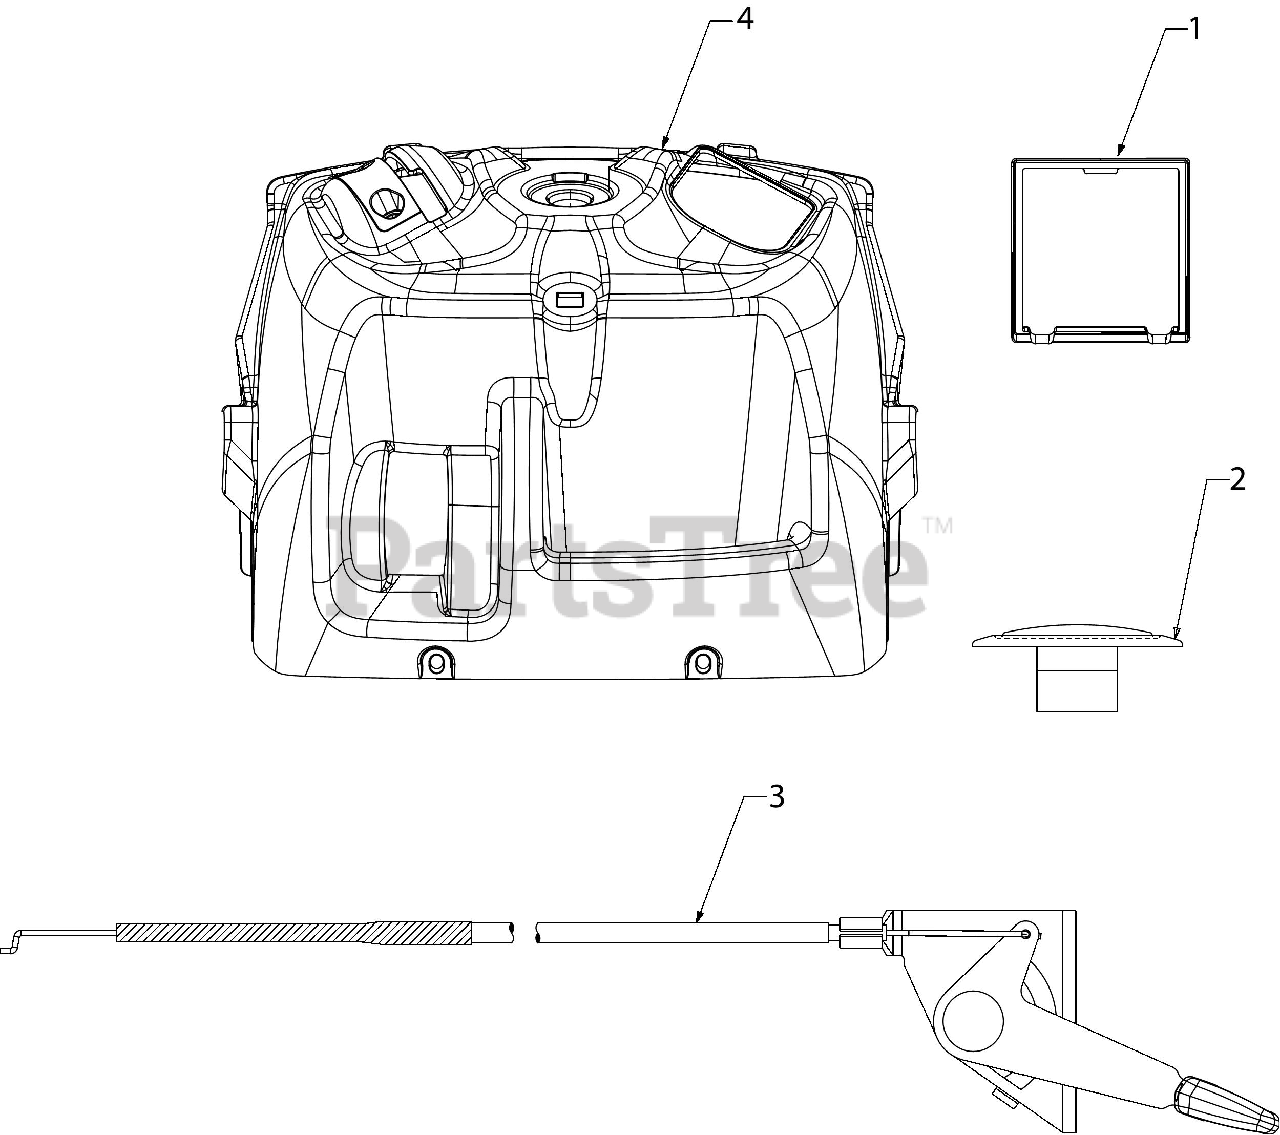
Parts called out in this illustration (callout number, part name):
1	AMMETER DASH PLUG
2	CHOKE PLUG
3	THROTTLE CABLE 28" x 1.1
4	UPPER DASH
